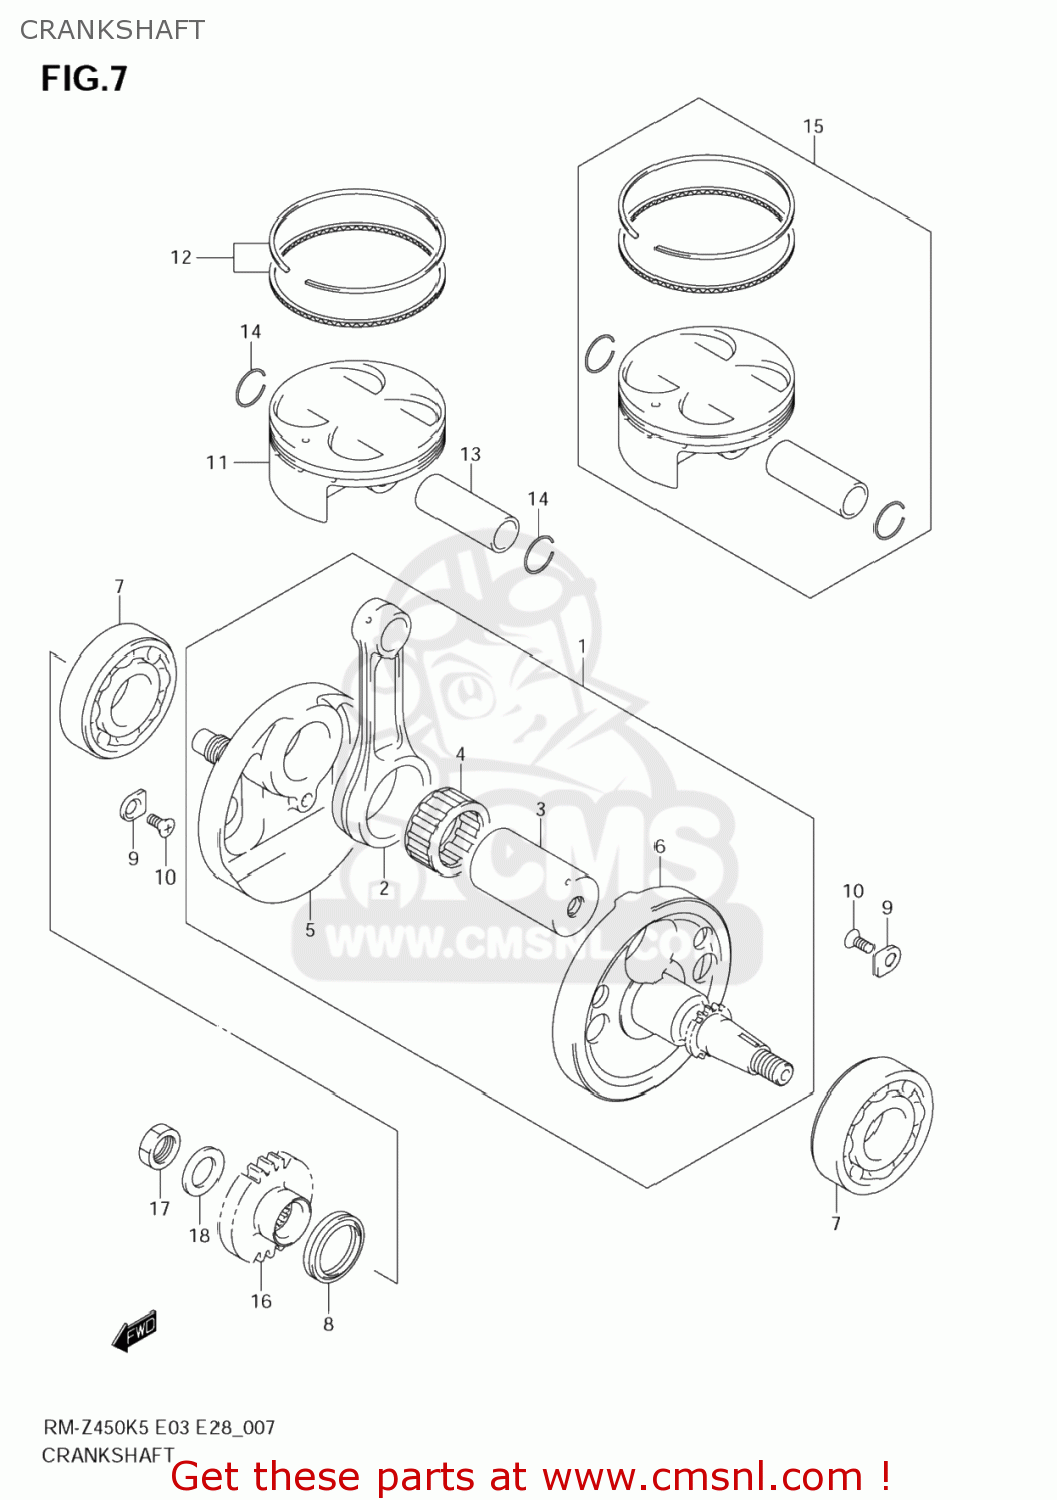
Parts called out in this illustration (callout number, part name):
1	CRANKSHAFT ASS
2	CONNROD
3	PIN COMP,CRANK
4	BEARING
5	CRANKSHAFT,R
6	CRANKSHAFT,L
7	BEARING(30X72X19)
8	SEAL,OIL(30X40X7)
9	RETAINER,COUNTER BEARING,R
10	SCREW(6X12)
11	PISTON
12	RING SET,PISTON
13	PIN,PISTON
14	RING,SNAP
15	PISTON KIT
16	GEAR,PRIMARY DRIVE
17	NUT
18	WASHER
